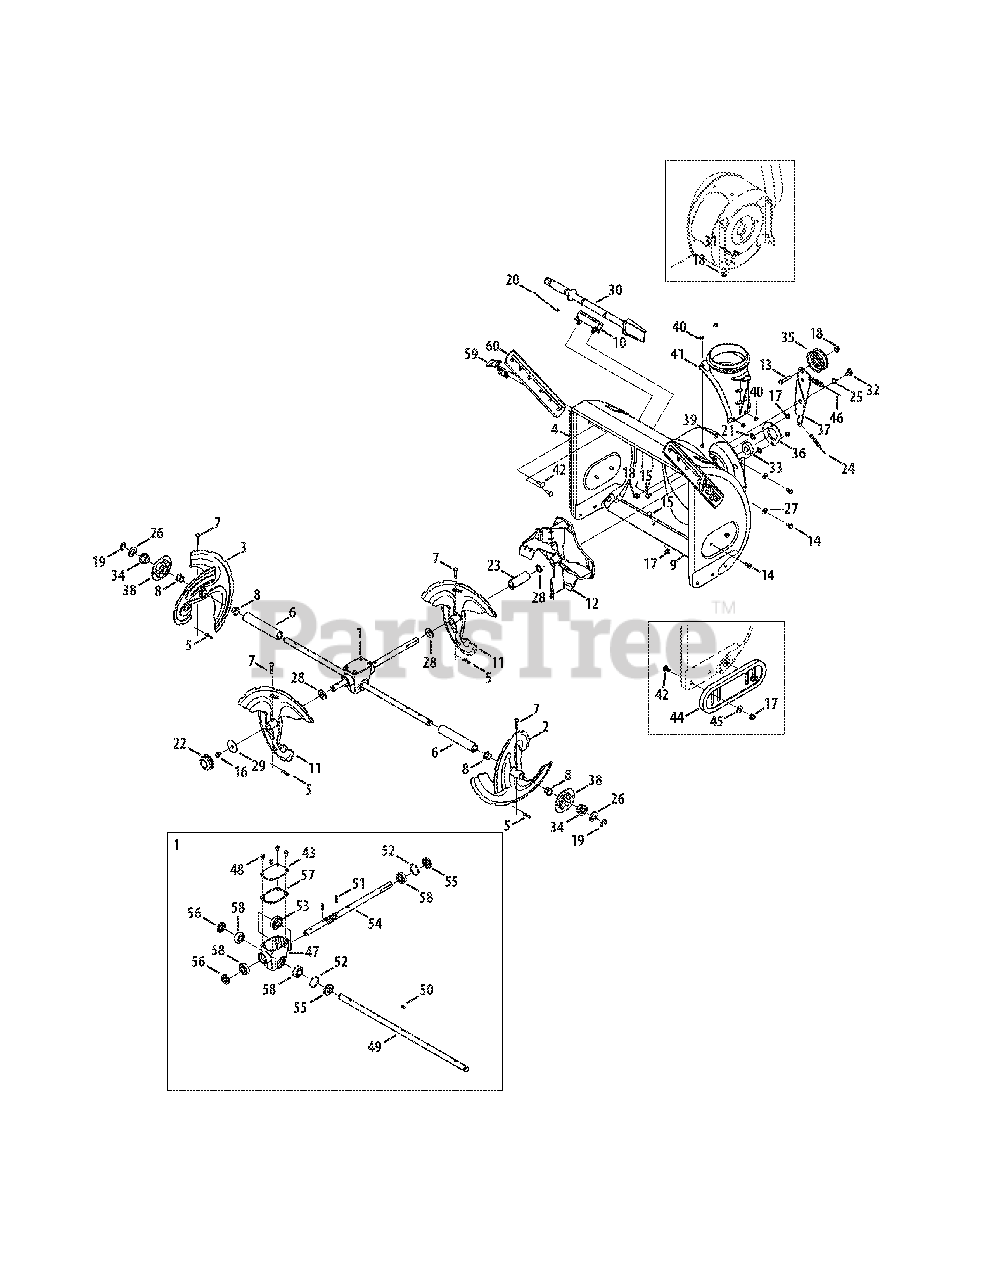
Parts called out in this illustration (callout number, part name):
1	Gearbox Assembly, Auger
2	Spiral Assembly - LH
3	Spiral Assembly - RH
4	Auger Housing, 28"
5	Bow Tie Cotter Pin
6	Spacer, 1.25 OD x .75 ID x 7.805
7	Shear Pin
8	Flange Bushing, .800 x .910
9	Shave Plate, 28"
10	Clean-out Tool Mtg. Bracket
11	Accelerator Assembly
12	Impeller Assembly
13	Hex Bolt, 3/8-16 x 1.75
14	Screw, 5/16-18 x .750
15	Carriage Bolt, 5/16-18 x .750
16	Hex Washer Screw, 5/16-18 x .500
17	Flange Lock Nut, 5/16-18
18	Flange Lock Nut, 3/8-16
19	E-ring, .75
20	Cable Tie
21	Push-On Nut, .25 Dia.
23	Spacer, 1.35 OD x .76 ID x 2.705
24	Extension Spring, .38 OD x 4.59
25	Wave Washer, .625 x .885 x .0175
26	Flat Washer, .76 x 1.49 x .06
27	Bell Washer, .340 x .872 x .060
28	Flat Washer, .793 x 1.24 x .06
29	Flat Washer, .406 x 1.92 x .060
30	Clean-Out Tool
31	Shoulder Screw, 3/8-16 x .496 x .336
32	Shoulder Screw, 3/8-16 x .625 x .17
33	Flange Ball Bearing, .75 x 1.85
34	Hex Flange Bearing, .75 ID
35	Flat Idler Pulley
36	Bearing Housing
37	Auger Idler Bracket
38	Bearing Housing
39	Carriage Screw, 1/4-20 x 0.75
40	Flange Lock Nut, 1/4-20
41	Chute Adapter
42	Spacer, Carriage, 5/16-18 x 1.00
43	Gearbox Cover
44	Polymer Slide Shoe, Deluxe
44	Polymer Reversible Shoe Kit
45	Washer, Flat, .349 x .879 x .063
46	Auger Clutch Cable
47	Auger Housing
48	Screw, 1/4-20 x 0.75
49	Axle, Auger, 28"
50	Hi-Pro Key
51	Pin, Roll, .25 x 1.0
52	Retainer Ring
53	Worm Gear, 20T
54	Worm Shaft
55	Seal, .75 x 40mm x .25
56	Seal, .75 x 1.375 x .25
57	Gearbox Gasket
58	Ball Bearing, .75 x 40 x 12
59	Wing Knob
60	Drift Cutter
